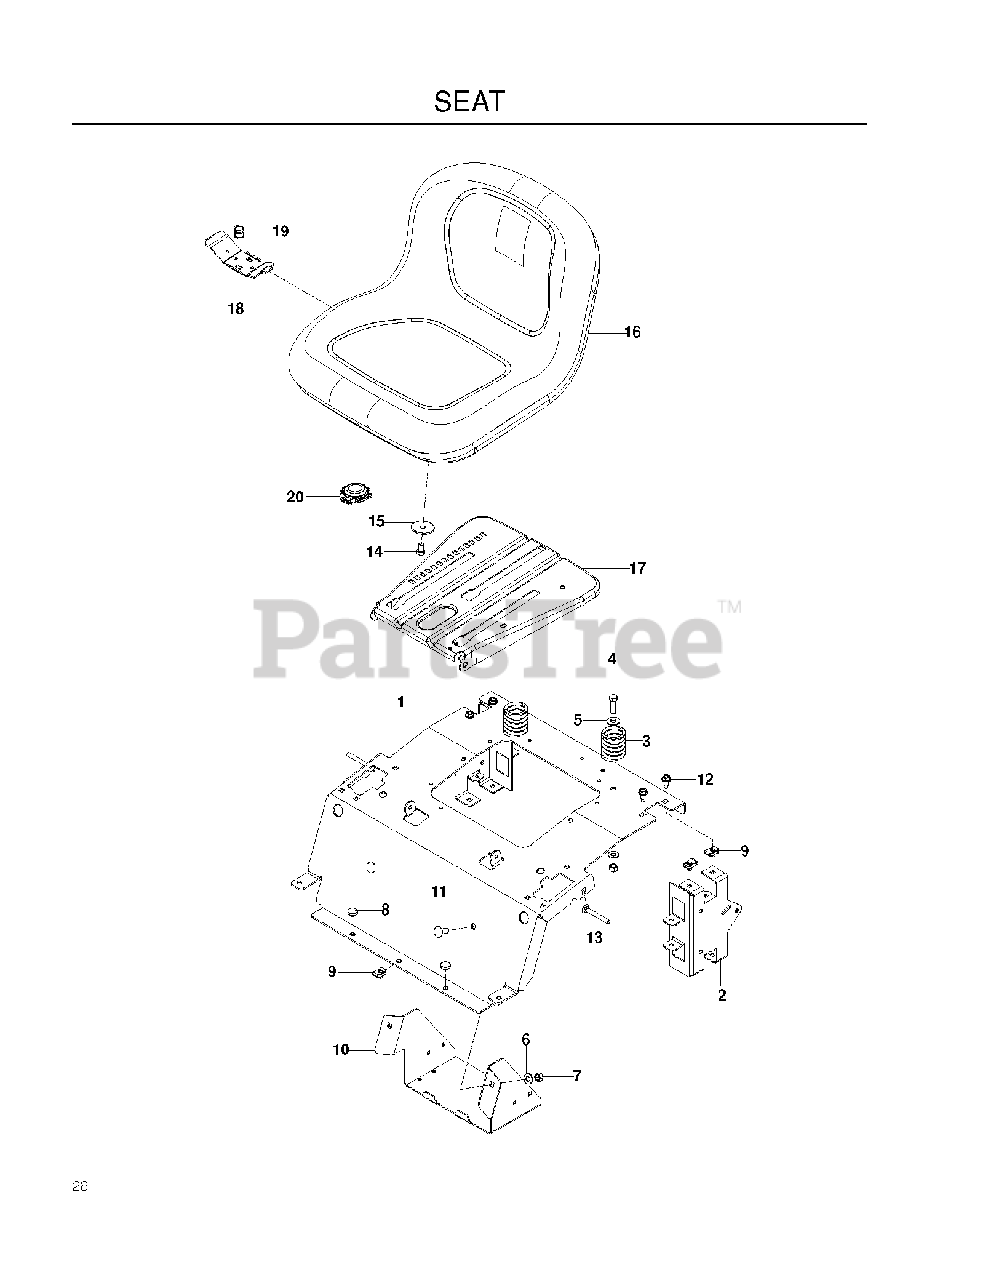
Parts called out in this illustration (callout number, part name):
1	SUPPORT, SEAT, BLUE
2	SUPPORT REAR SEAT BLA
3	SPRING, SEAT
4	HCS 3/8C X 1 1/4 GR5
5	WASHER 3/8 FLAT
6	WASHER 3/8 SAE FLAT
7	NUT 3/8-16 NYLOC
8	GROMMET, BUMPER
9	U-CLIP 5/16-18 NUT RETAINER
10	BOX, BATTERY, BLACK
11	RHSNB 3/8C X 1
12	BOLT 5/16-18 X 3/4
13	RHSNB 5/16-18 X 2-1/2 GR5 ZD
14	HCS 3/8-16 X 5/8 GR 5 ZD
15	WASHER, 3/8 SPEC
16	SEAT,BLACK W/ARMREST PROVISION
17	PAN.ASM.SEAT.3PT
18	HANDLE.SLIDE.SEAT.TEX.BLACK
19	SPRING.LATCH.SEAT.TEX
20	SWITCH, SEAT N/C
